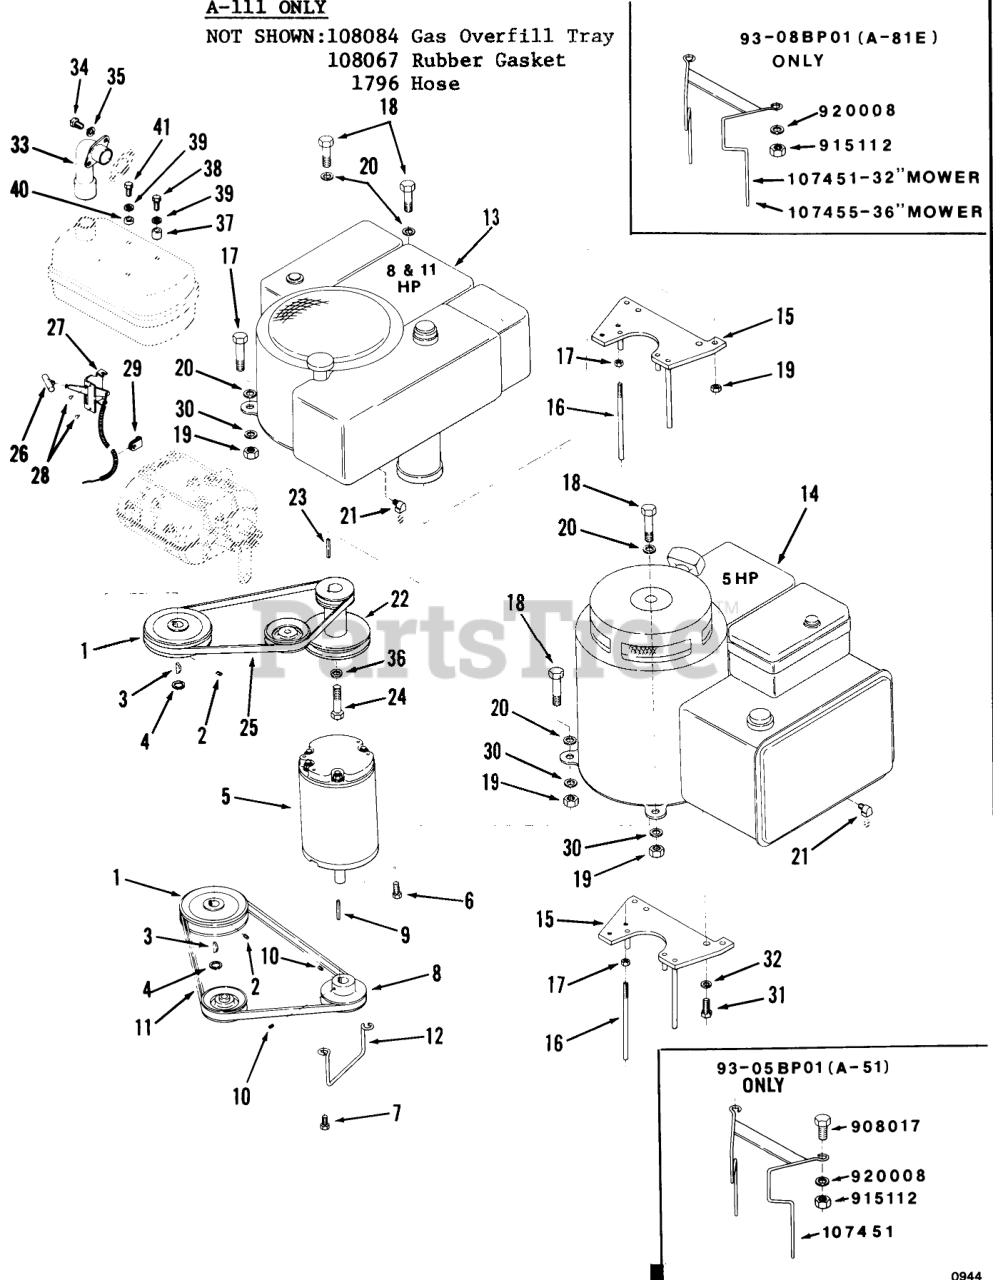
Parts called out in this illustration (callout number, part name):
19	Nut
20	WASHER 5/16 SAE
21	ELBOW-STREET
22	Pulley-Engine
23	Key Sq. 1/4 X 1 1/2
24	HEX HD CAP SCREW
25	V-BELT
26	KNOB-CONTROL
27	CONTROL-THROTTLE
28	RIVET
29	THROTTLE CONTROL CLP
30	WASHER 5/16 SAE
30	WASHER
31	Bolt 3/8-12 X 1 1/4 S.T.
32	LOCKWASHER
33	ASSY-EXH MANIFOLD
34	H H C S
35	Lockwasher
36	WASHER 5/16 SAE
37	Spacer
38	Bolt
40	Spacer
41	Bolt
